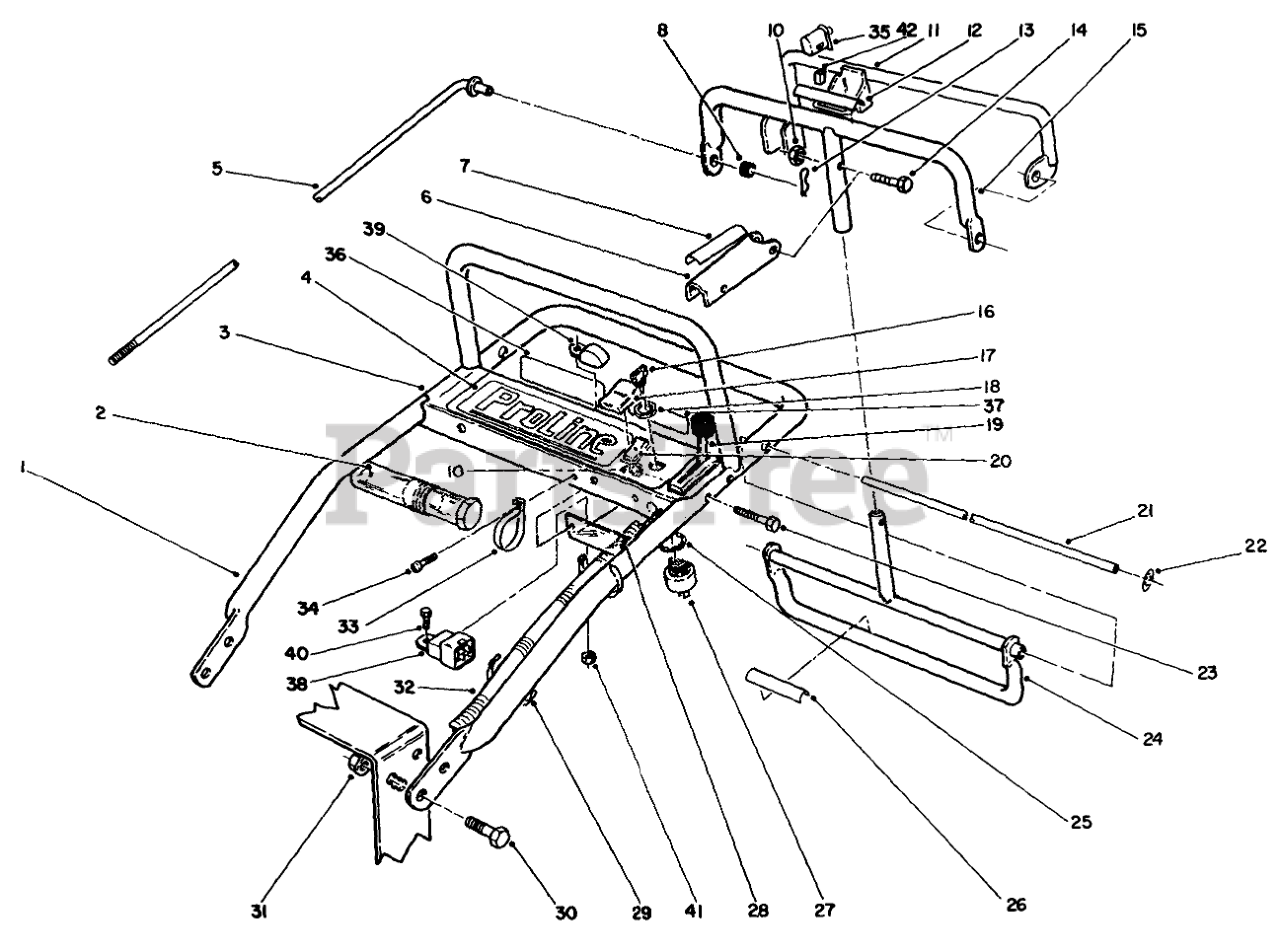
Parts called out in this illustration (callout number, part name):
1	Handle-Upper
2	TUBE-MANUAL
3	Panel-Control
4	DECAL-CONTROL PANEL
5	ROD-CONTROL
6	Lever-Parking Brake
7	DECAL-LEVER, PARKING
8	GROMMET-RUBBER
10	NUT-LOCK, NI
11	Bail
12	DECAL
13	PIN-COTTER
14	SCREW-SHH
15	Bar
16	KEY-IGNITION
17	BOOT-SWITCH
18	NUT-HH
19	CONTROL-THROTTLE
20	SWITCH
21	PIVOT ROD
22	NUT-PUSH-ON, CIRCULAR
23	SCREW-SHH
24	Control Pivot
25	WASHER-TOOTH, INTERNAL
26	DECAL
27	Switch-Off/On (Incl. Ref. #16, 18, & 25)
28	Panel-Bottom
29	TIE-CABLE
30	SCREW-HHF
31	NUT-HF
32	Wire Harness
33	CLAMP-R
34	SCREW-HWHTF
35	SWITCH-BAIL
36	DECAL-INSTRUCTION, SAFETY
37	DECAL-INSTRUCTION
38	RELAY
39	Module
40	SCREW-HH
41	NUT-LOCK, NI
42	CONNECTOR-BODY
